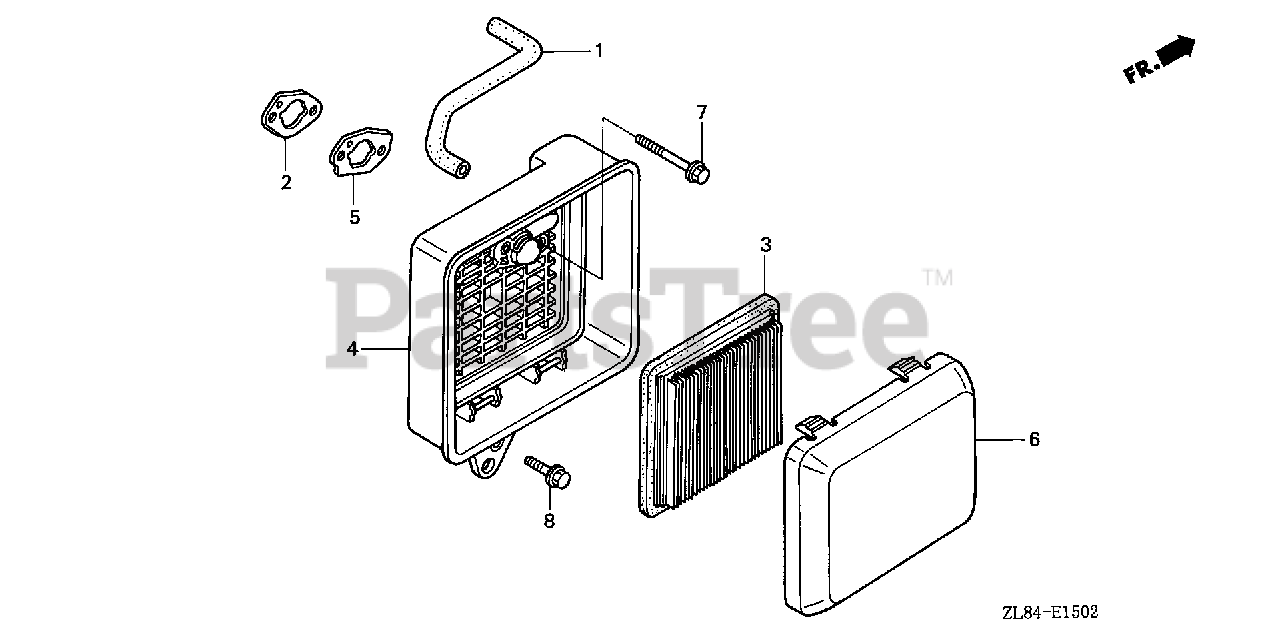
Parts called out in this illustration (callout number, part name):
1	TUBE, BREATHER
2	SPACER, CARBURETOR
3	ELEMENT, AIR CLEANER
4	CASE ASSY., AIR CLEANER
5	GASKET, AIR CLEANER
6	COVER, AIR CLEANER
7	BOLT, FLANGE (6X86) (CT200)
8	BOLT, FLANGE (6X35)
